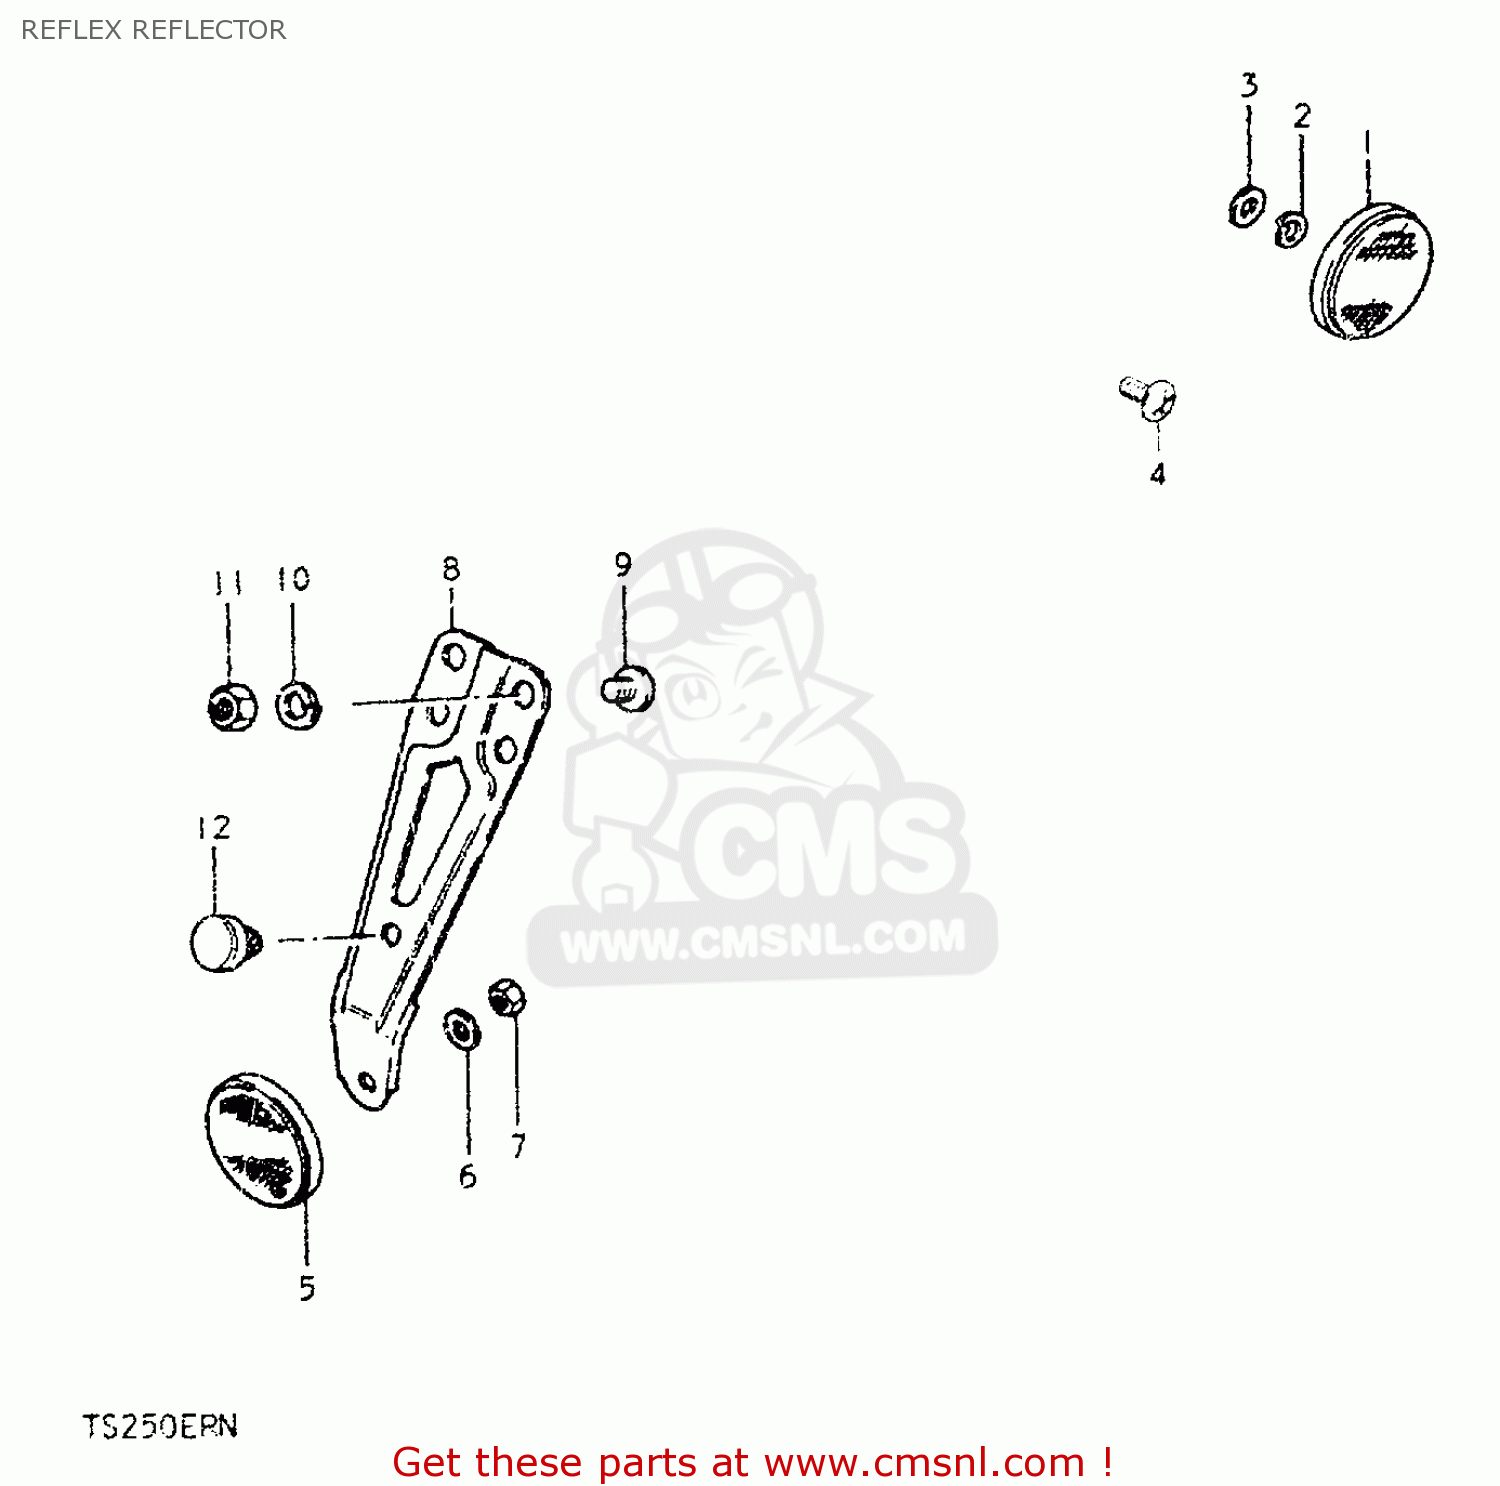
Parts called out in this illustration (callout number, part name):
1	REFLEX REFLECTOR,FR
2	LOCK WASHER
3	WASHER
5	REFLEX REFLECTOR,RR
6	WASHER
7	NUT
